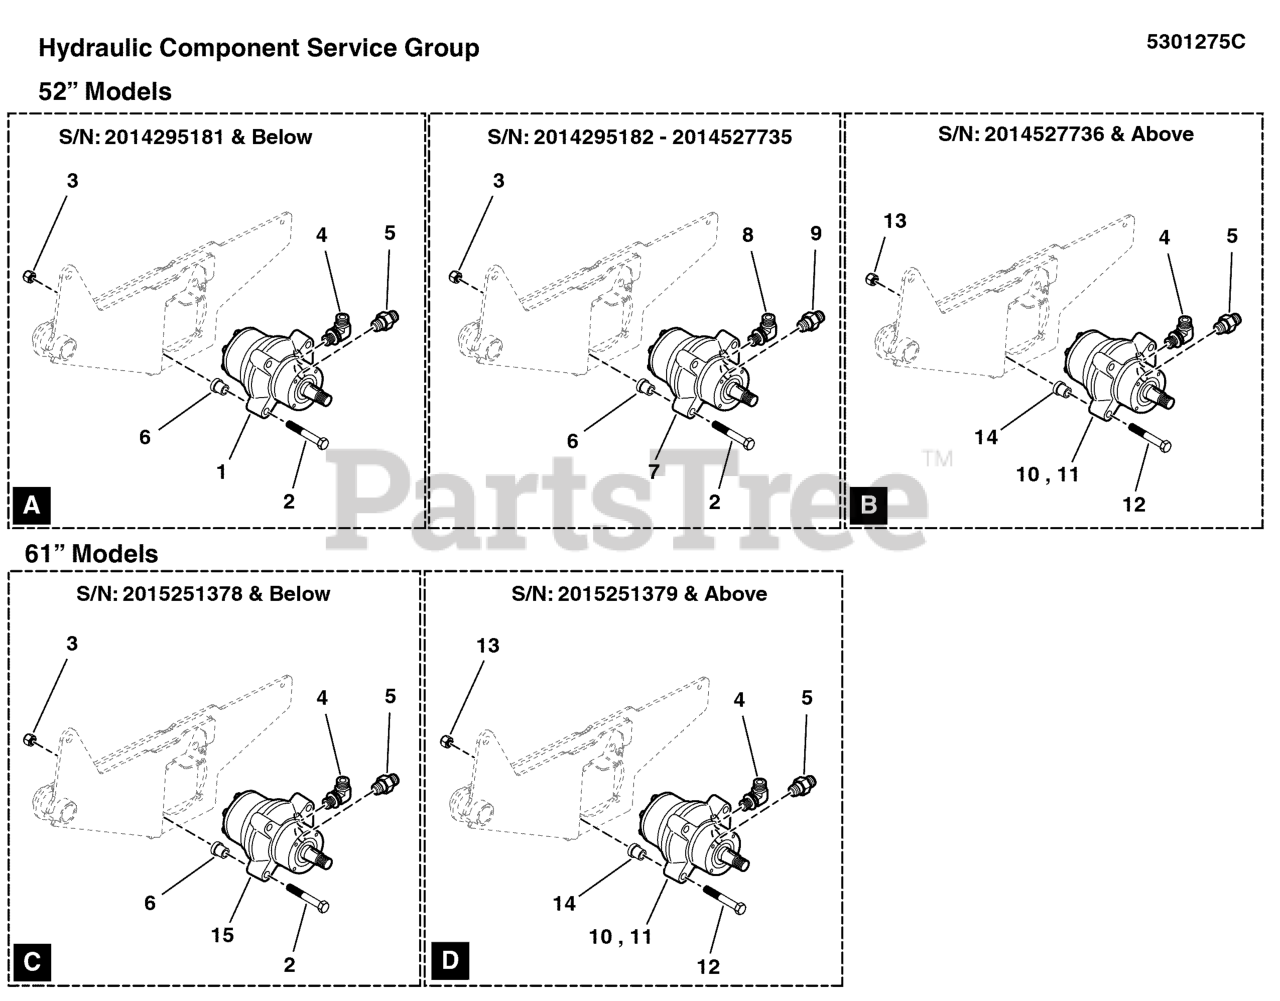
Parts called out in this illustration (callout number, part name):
2	BOLT, 1/2-13 X 3-1/2, HEX HD, GD5, CZ (SV)
3	NUT, Hex Flange, Nylock, 1/2-13
4	FITTING, #10 ORING-#8 JIC, 90D
5	FITTING, #10 O-RING X #8 JIC, STR
6	SPACER, .53 X 1.00 X 1.00, CZ
7	MOTOR, WHEEL, HGM-15C-4026
8	FITTING, #8 JIC - #8 O-RING, 90 DEG.
9	FITTING, #8 O-RING X #8 JIC, STR
10	WHEEL MOTOR, LH, 14.5 CI-TF0240LS080AAKZ
11	WHEEL MOTOR, RH, 14.5 CI-TF0240LS081AAKZ
12	BOLT, 1/2-13 X 3.5, DRI-LOC PATCH
13	NUT, 1/2-13 SQUARE
14	SPACER, .53 X 1.00 X 1.00, W/ FLAT, CZ
